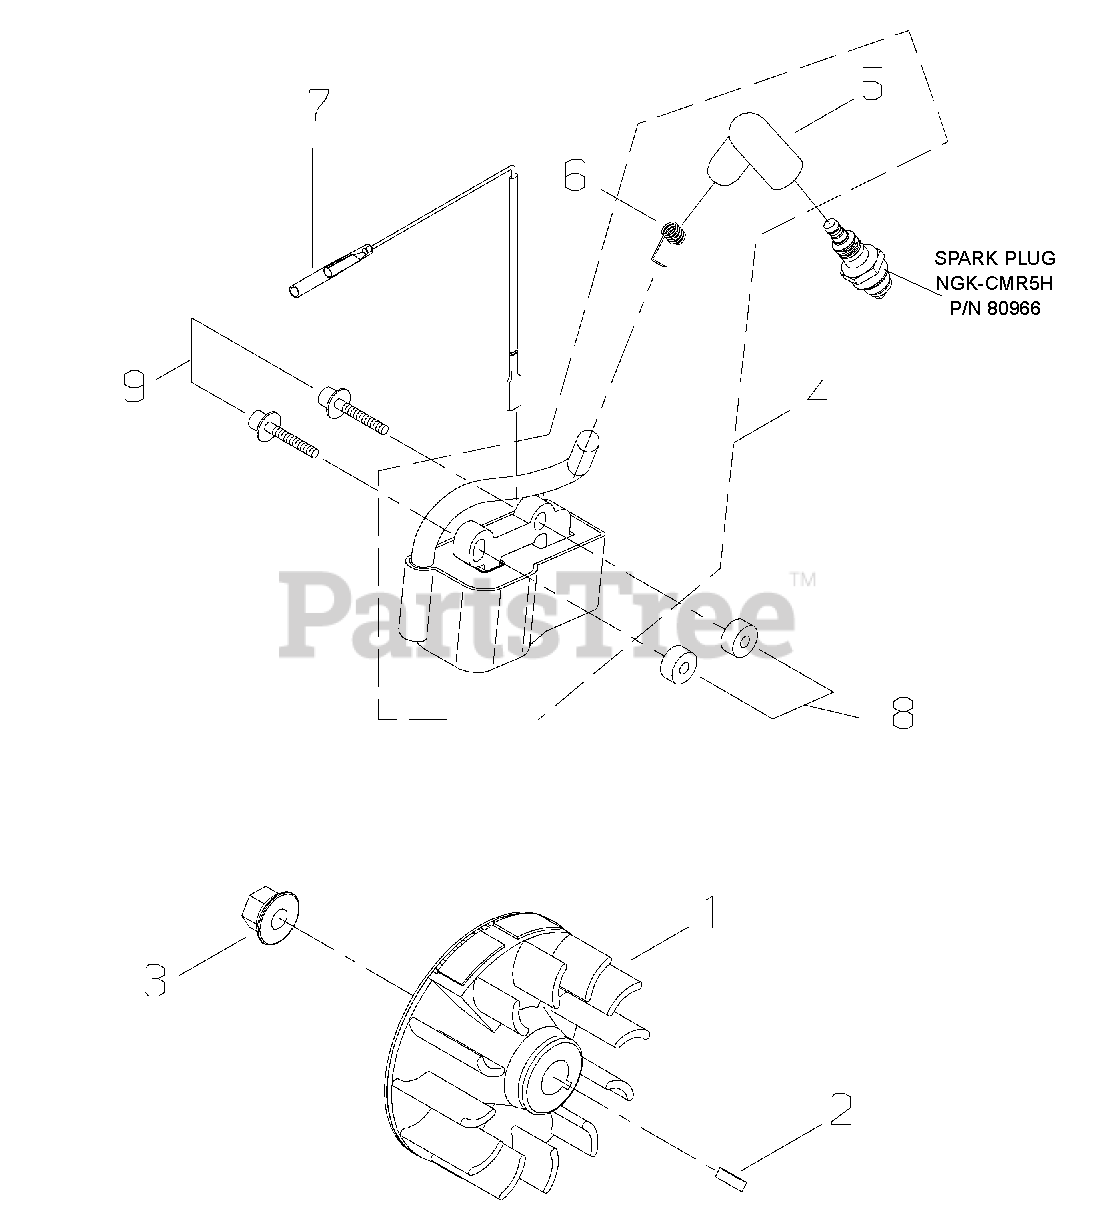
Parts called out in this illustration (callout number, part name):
2	KEY - 3X10
3	NUT - 8
4	IGNITION COIL ASSY
5	CAP, SPARK PLUG
6	TERMINAL, SPARK PLUG CAP
7	LEAD - IGNITION
8	INSULATOR
9	SCREW - 4X26
